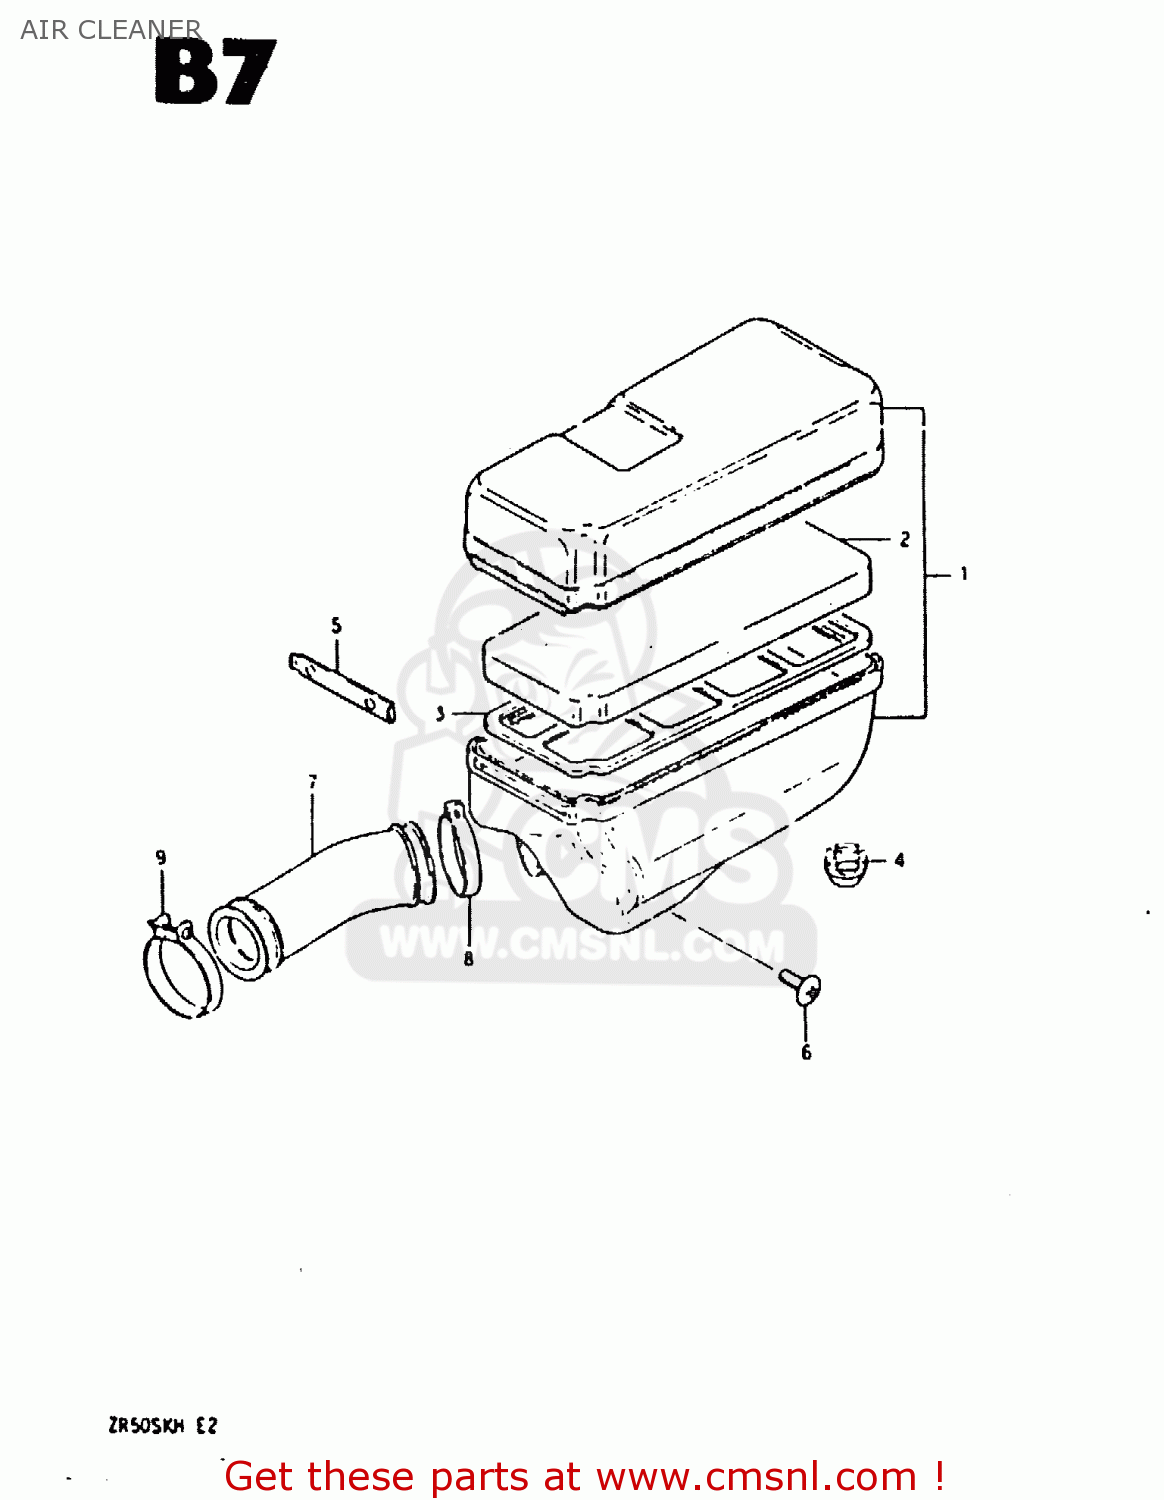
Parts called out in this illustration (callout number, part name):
1	CLEANER ASSY,A
2	FILTER
3	HOLDER
4	CAP,DRAIN
5	SLIDER
6	SCREW
7	TUBE,AIR CLEANER OUTLET
8	CLAMP
9	CLAMP
